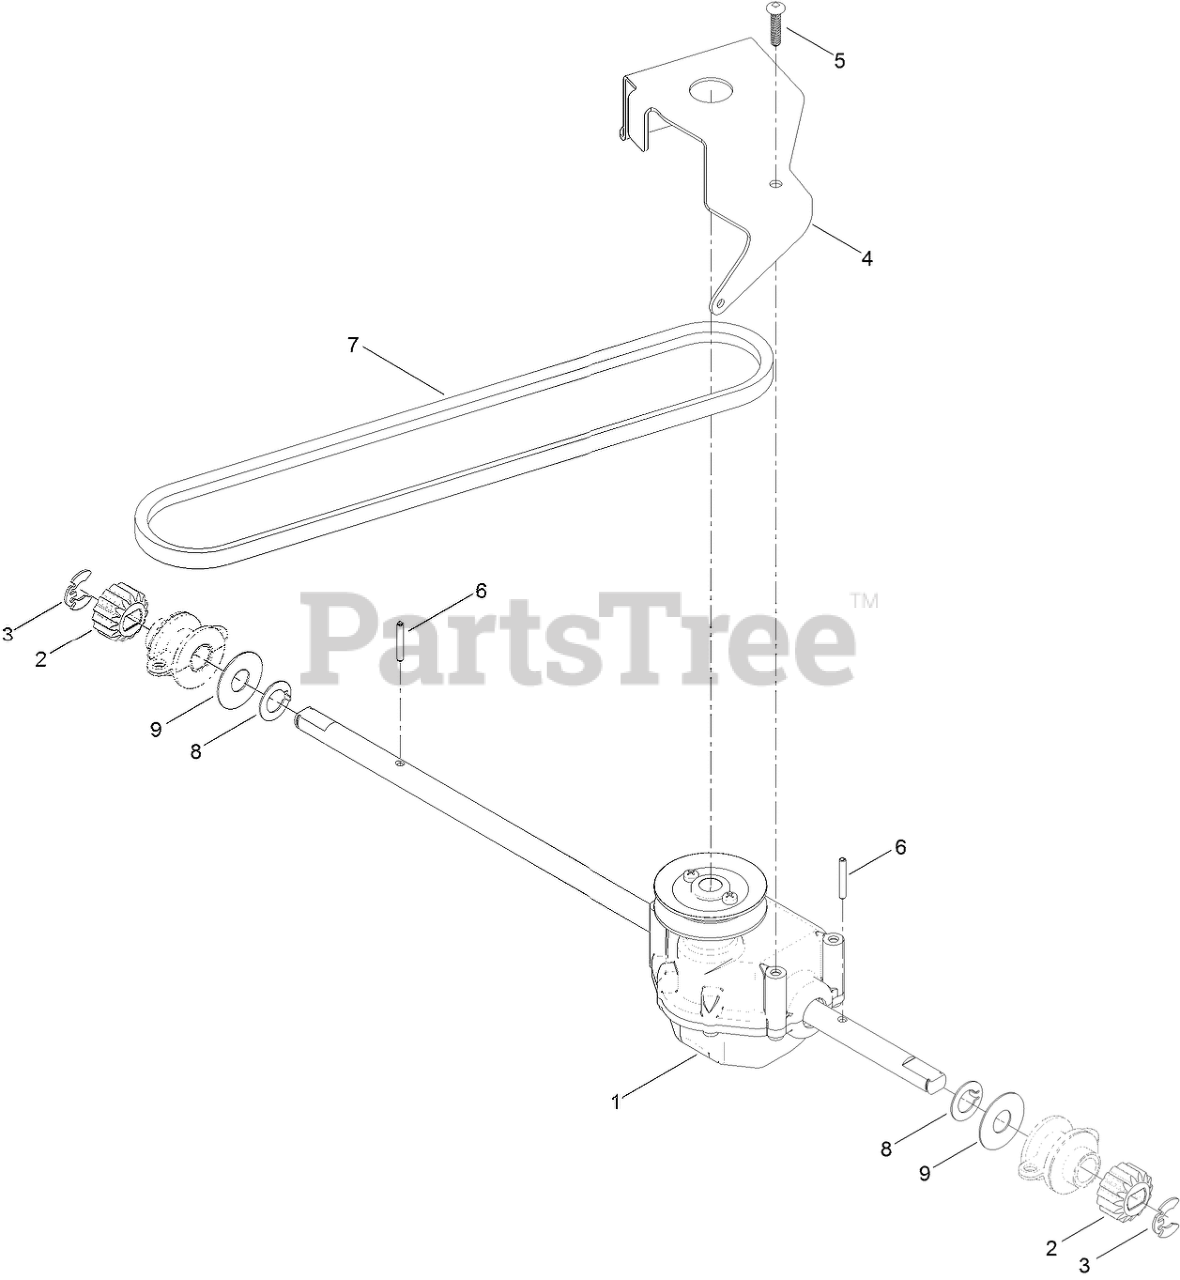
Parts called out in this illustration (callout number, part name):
1	TRANSMISSION-GEARBOX
2	GEAR-PINION, 15T
3	RING-RETAINING,CLIP
4	BRACKET-TRANSMISSION
5	SCREW-PLASTITE
6	PIN-ROLL
7	V-BELT
8	WASHER-THRUST, KEYED
9	WASHER-PLAIN
